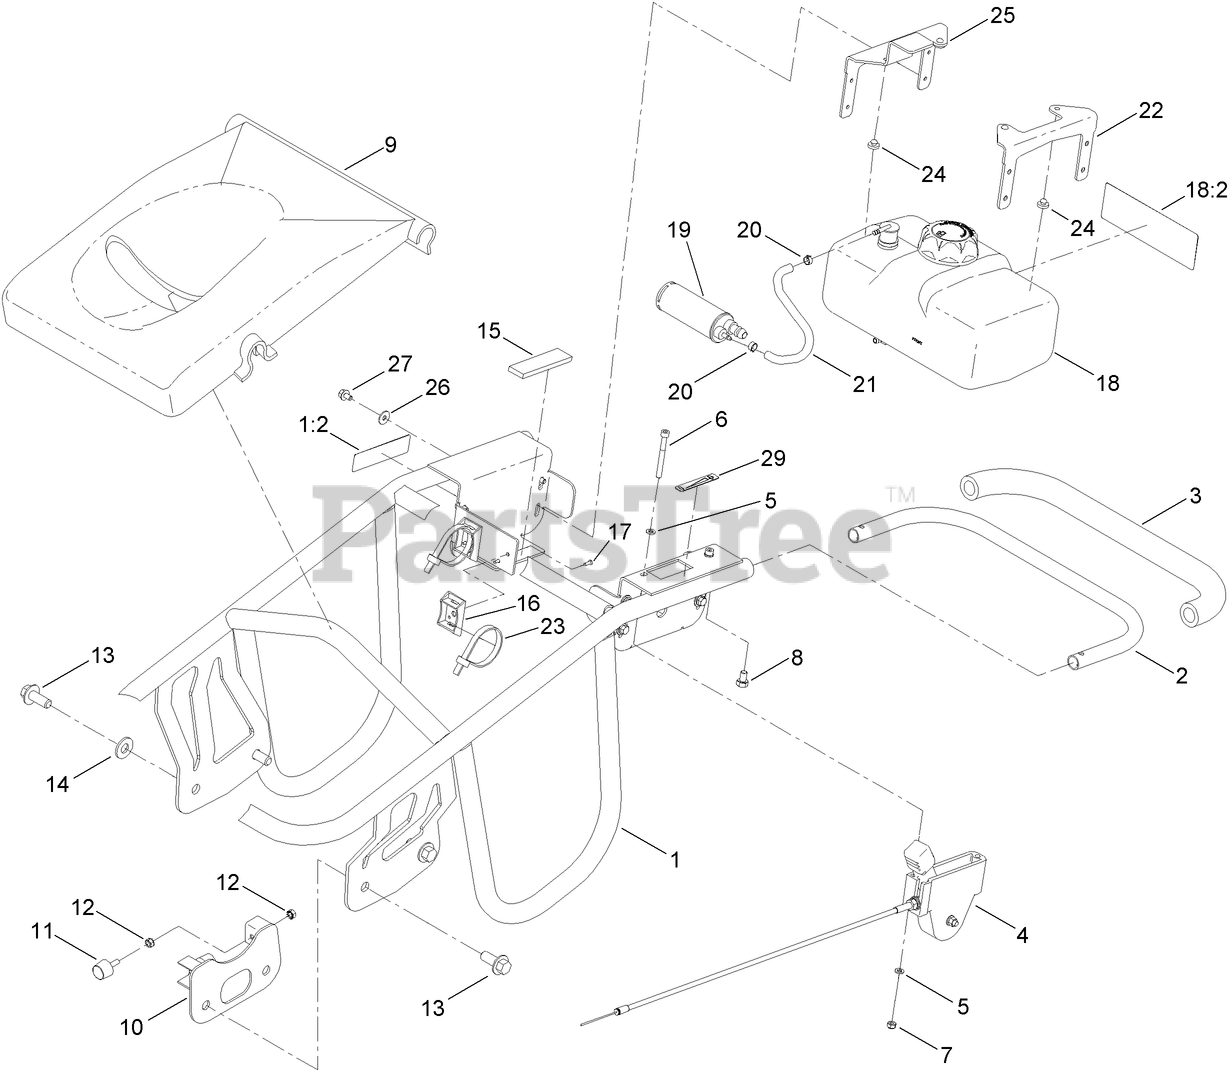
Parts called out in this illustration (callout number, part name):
1	HANDLE ASM
1:2	DECAL-ARRESTER, SPARK
2	HANDLE-GRIP, TUBE
3	GRIP-HAND
4	LEVER-THROTTLE
5	WASHER-FLAT
6	SCREW-HSH
7	NUT-LOCK
8	SCREW-HWH
9	COVER-ENGINE
10	STOPPER
11	MOUNT-SHOCK
12	NUT-HEX
13	SCREW-HHF
14	WASHER
15	PAD-TANK, FUEL
16	BRACKET-CANISTER
17	RIVET
18	1 GALLON FUEL TANK ASM
18:2	DECAL-WARNING
19	CANISTER-CARBON
20	CLAMP-HOSE, FUEL
21	HOSE-FUEL
22	BRACKET-TOP, FUEL TANK
23	TIE-CABLE
24	BUMPER-RUBBER
25	GUARD-TANK, FUEL
26	WASHER-FLAT
27	SCREW-HHF
29	DECAL-THROTTLE
